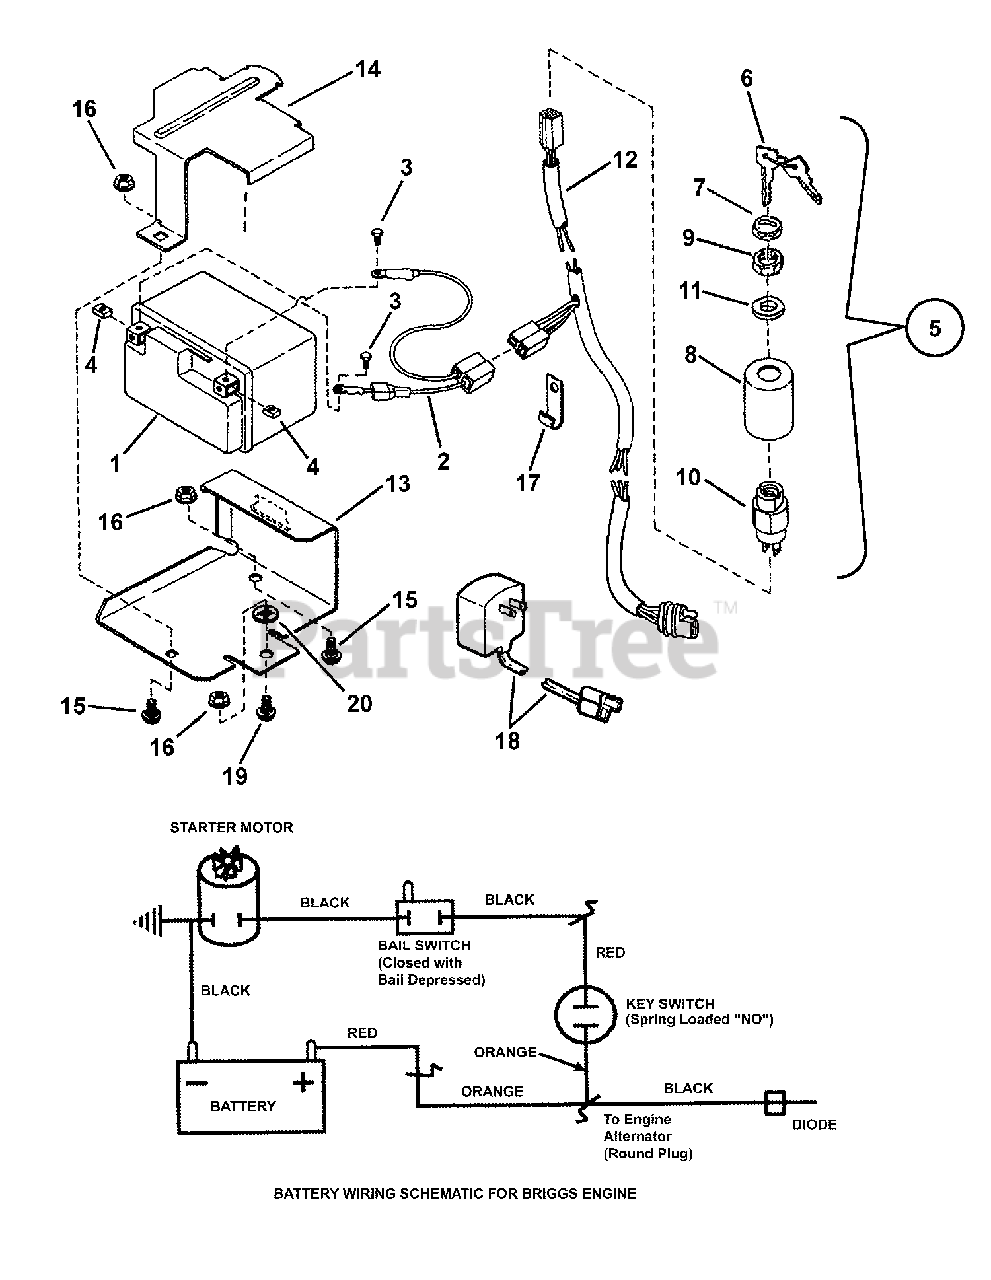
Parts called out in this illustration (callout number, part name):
1	* KIT, Battery 12V
1	BATTERY, 12 Volt, 35 CCA
2	HARNESS, Battery
3	SCREW, #10-24 x 1/2" Pan Head Machine
4	NUT, #10-24 Square
5	SWITCH ASSEMBLY (Incl. items 6 thru 11)
6	KEY, (Set of Two)
7	BEZEL, (Seal & Face Nut)
8	COVER, Switch
9	NUT, 5/8-32 Hex Lock
10	SWITCH, Ignition (spring loaded ON/OFF 2 prong)
11	SPACER
12	WIRING HARNESS, B&S WBM
13	BRACKET, Battery
14	COVER, Battery
15	BOLT, 5/16-18 x 1/2" Short Neck Carriage GR 5
16	NUT, 5/16-18 Hex Flange Lock, GR 5
17	CLIP, Wiring
18	CHARGER, Battery (120 Volt; 60 Hertz)
19	BOLT, 5/16-18 x 5/8" Short Neck Carriage GR 5
20	RETAINER, 5/16" Bolt
